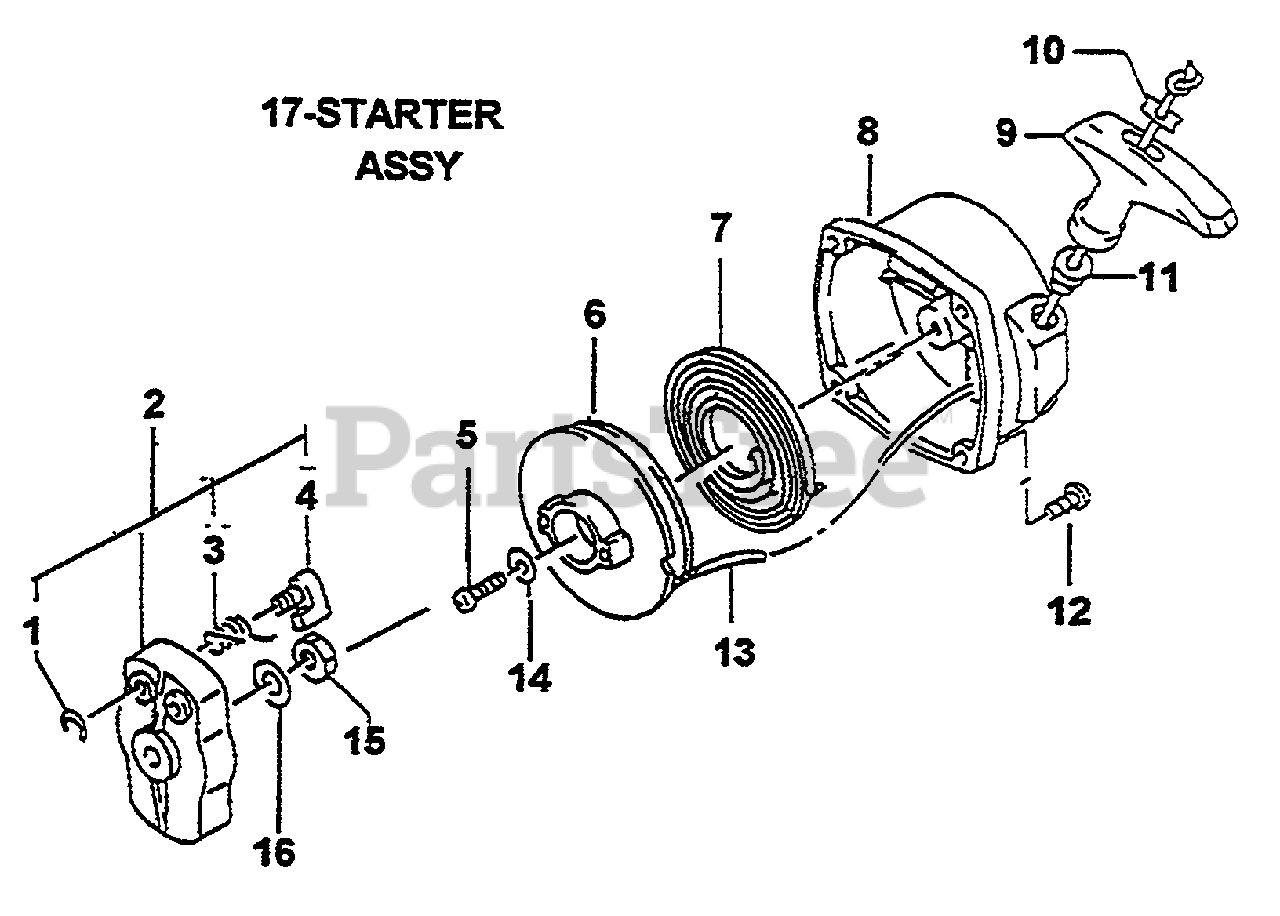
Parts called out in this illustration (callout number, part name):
1	SNAP RING
2	PULLY ASSY
3	SPRING, RETURN
6	REEL STARTER
7	SPRING, RECOIL
8	CASE, STARTER
10	PLATE, ROPE
11	GUIDE, ROPE
17	STARTER ASSY
